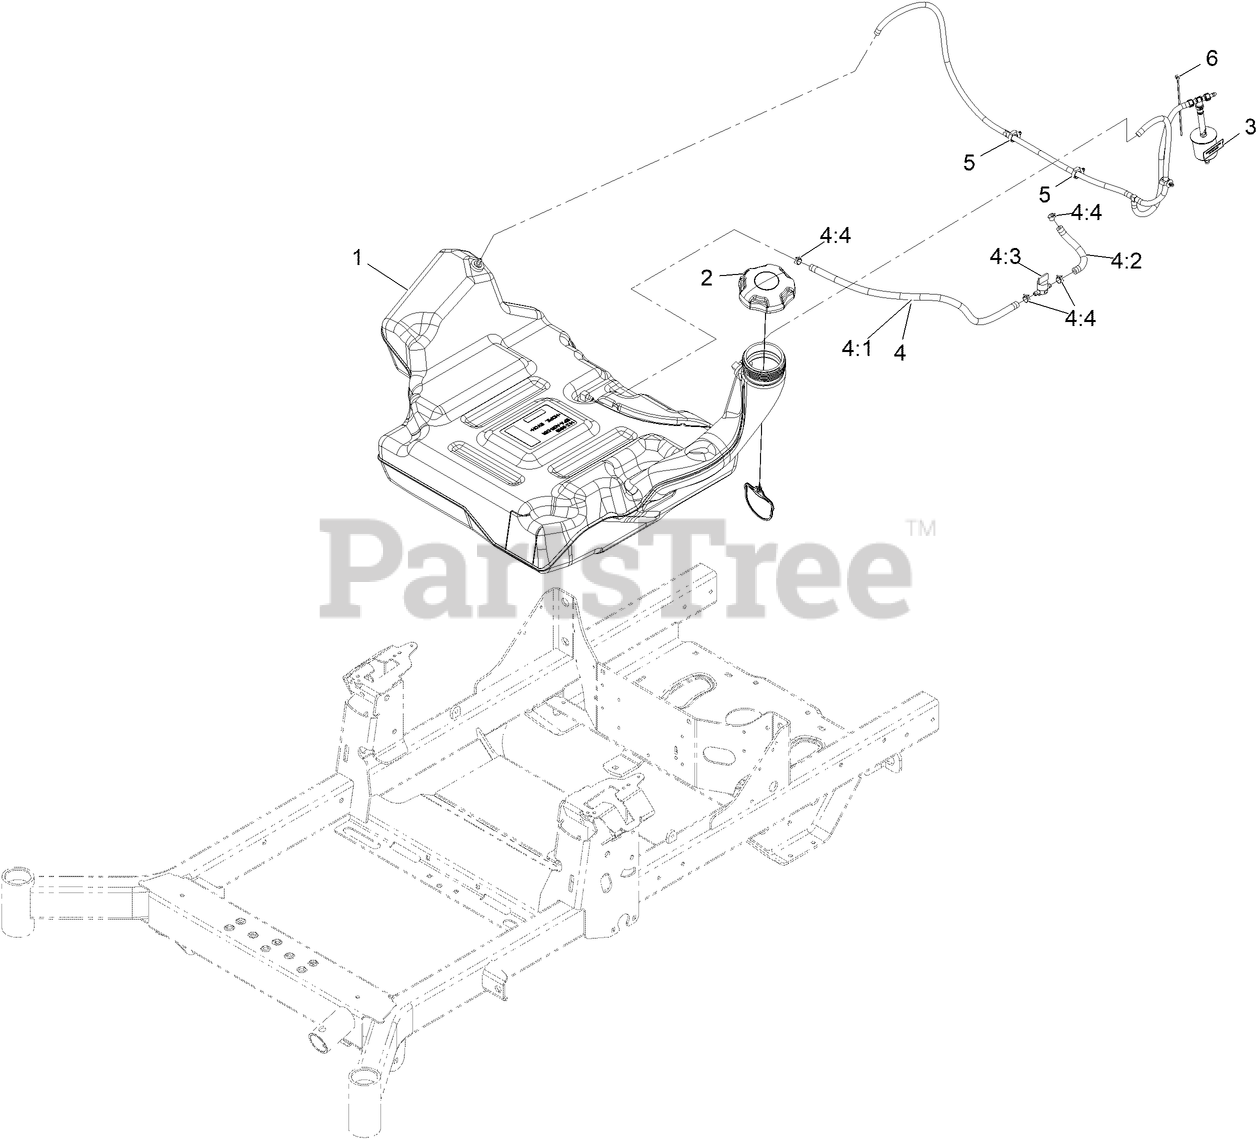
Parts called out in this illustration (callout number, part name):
1	ASM-FUEL TANK
2	CAP-FUEL, RATCHETING
3	VENT HOSE ASM
4	FUEL HOSE ASM
4:1	HOSE-FUEL
4:2	HOSE-FUEL
4:3	VALVE-FUEL
4:4	CLAMP-HOSE
6	TIE-CABLE
